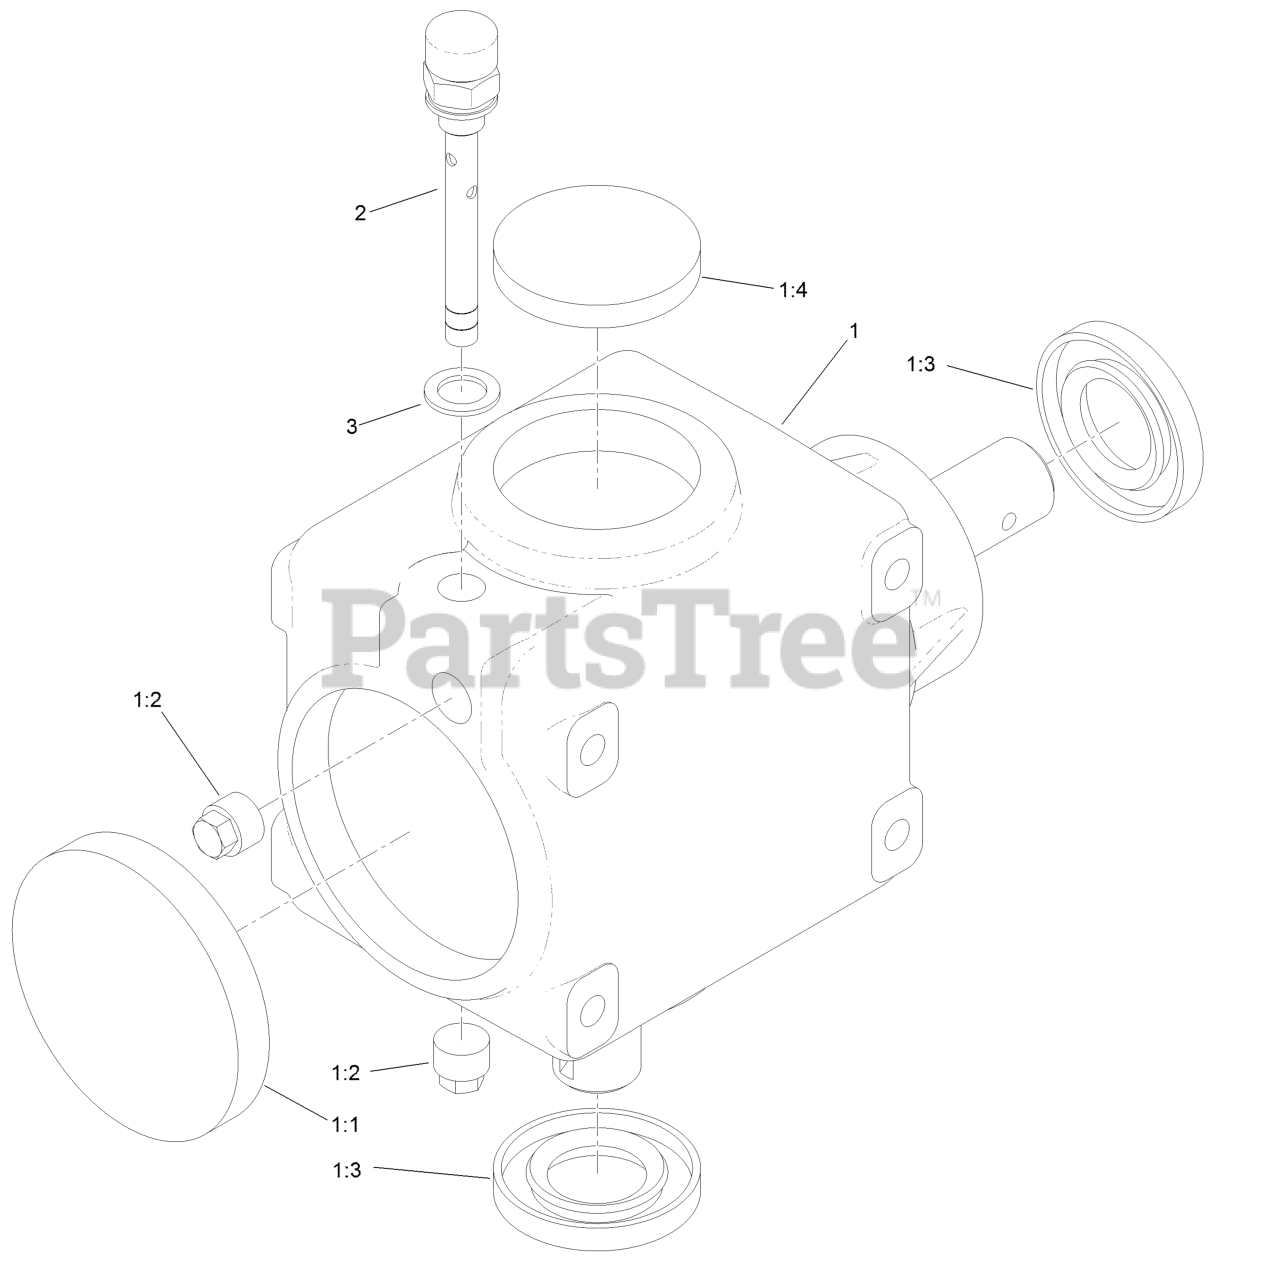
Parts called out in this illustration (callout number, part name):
1	Gearbox ASM
1:1	Cap-Oil
1:4	Cap-Oil
2	Plug-Breather
